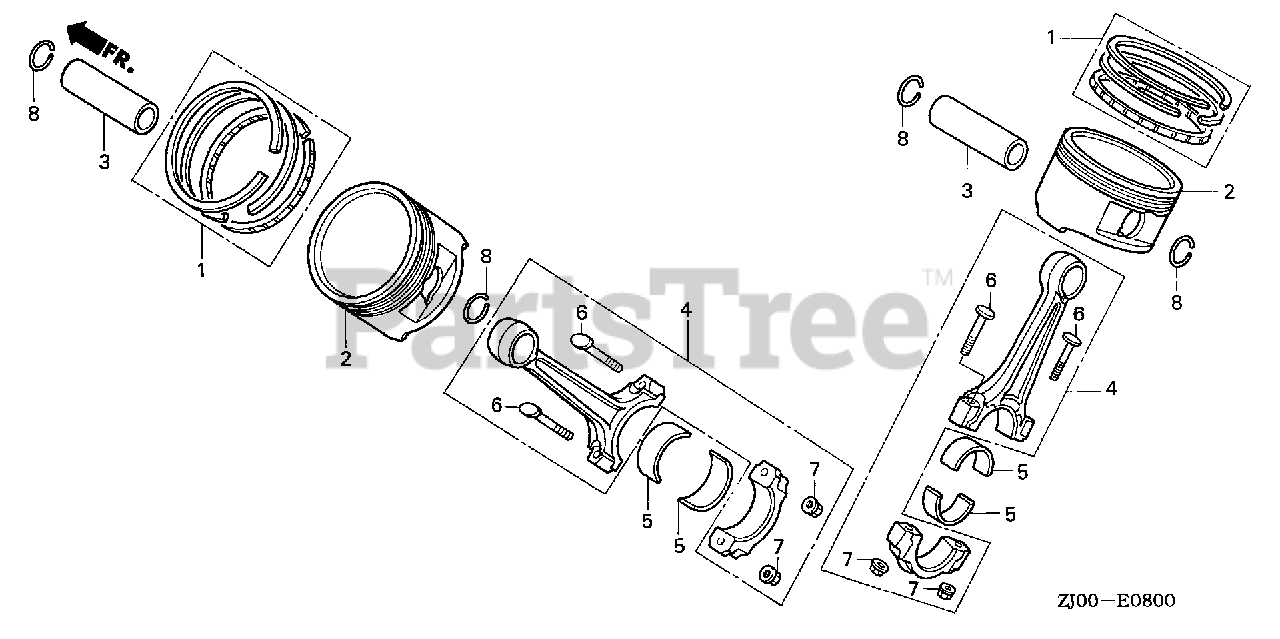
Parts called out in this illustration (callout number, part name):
1	RING SET, PISTON (STD) (NIPPON)
1	RING SET, PISTON (0.25) (NIPPON)
1	RING SET, PISTON (0.50) (NIPPON)
1	RING SET, PISTON (0.75) (NIPPON)
1	RING SET, PISTON (0.75) (TEIKOKU)
2	PISTON (STD)
2	PISTON (0.25)
2	PISTON (0.50) (NOT AVAILABLE)
2	PISTON (0.75)
3	PIN, PISTON
4	ROD SET, CONNECTING
5	BEARING A, CONNECTING ROD (BLUE)
5	BEARING B, CONNECTING ROD (BLACK)
5	BEARING C, CONNECTING ROD (BROWN)
5	BEARING D, CONNECTING ROD (GREEN)
5	BEARING E, CONNECTING ROD (YELLOW)
5	BEARING F, CONNECTING ROD (PINK) (NOT AVAILABLE)
5	BEARING G, CONNECTING ROD (RED)
6	BOLT, CONNECTING ROD
7	NUT, CONNECTING ROD
8	CLIP, PISTON PIN (18MM)
